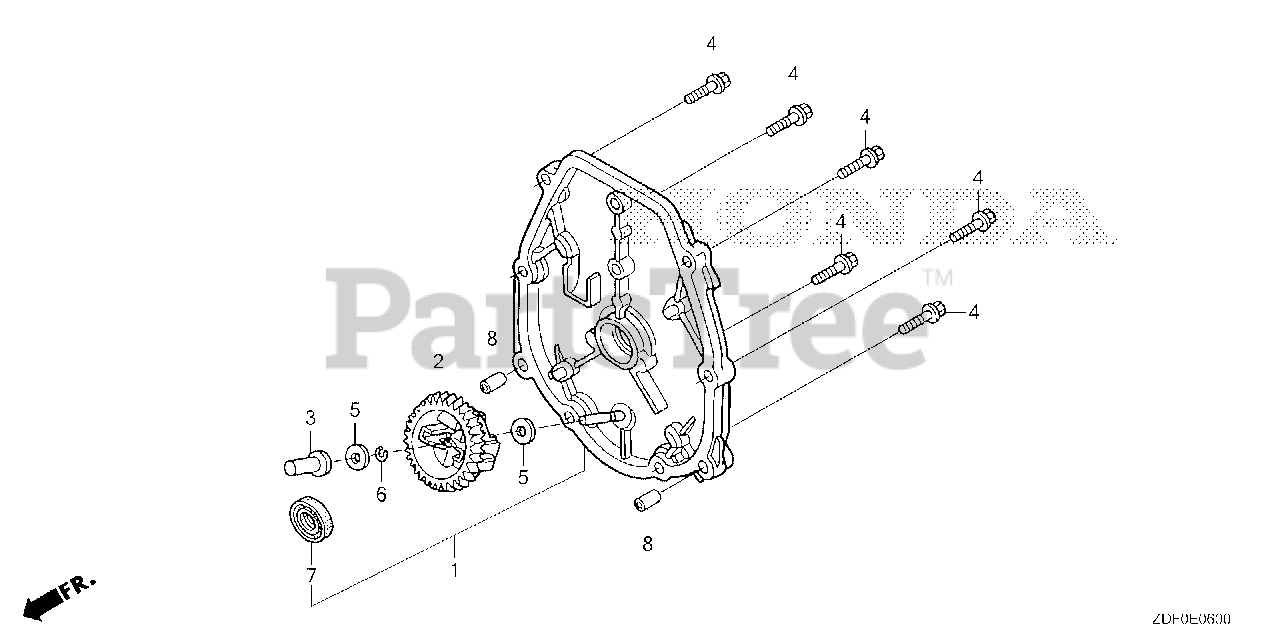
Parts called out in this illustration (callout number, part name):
1	COVER, CRANKCASE SIDE
2	GOVERNOR ASSY.
3	SLIDER, GOVERNOR
4	BOLT, FLANGE (5X23)
5	WASHER (4.2X13)
6	CLIP, GOVERNOR HOLDER
7	OIL SEAL (17X27X5) (KOYO)
8	PIN A, DOWEL (6X10)
